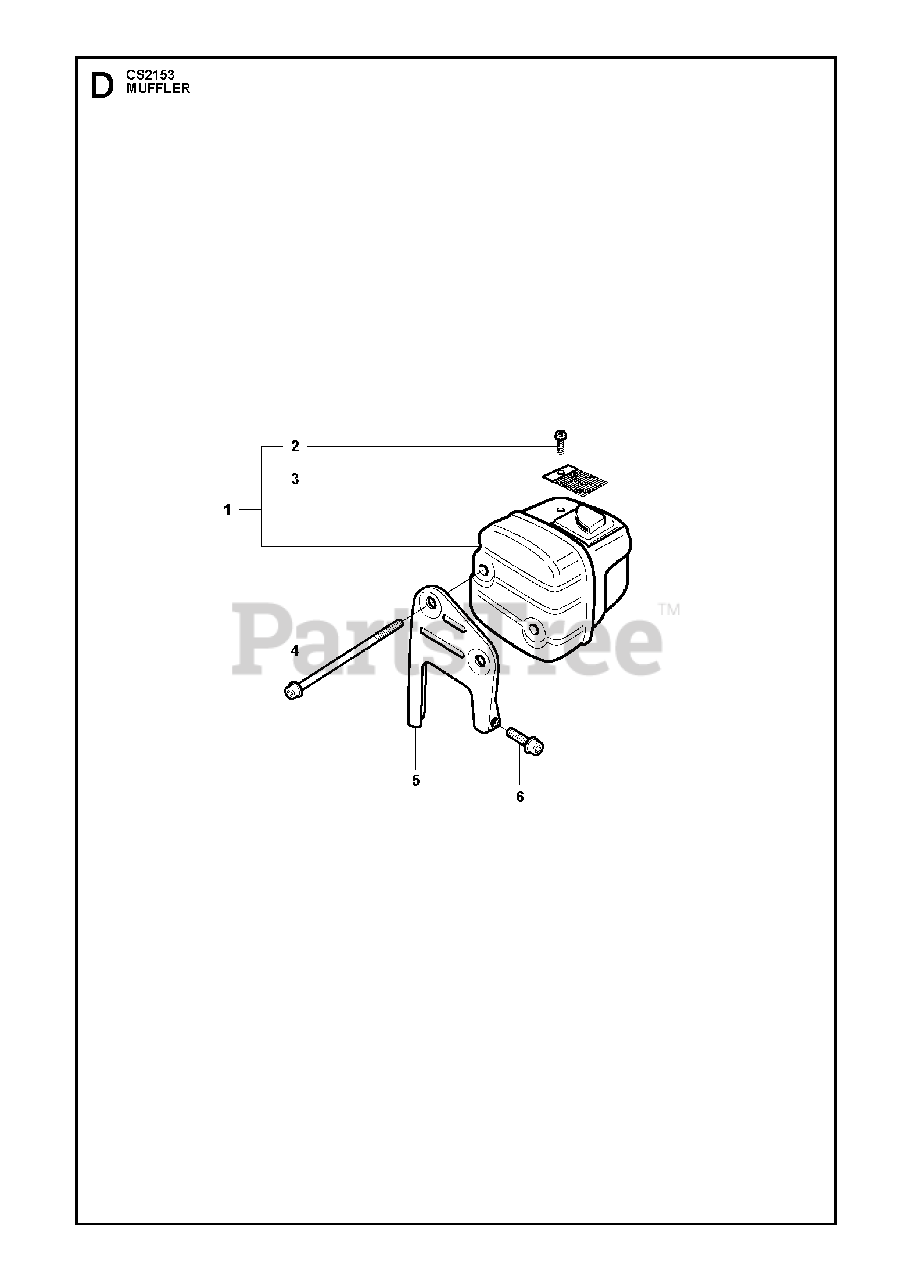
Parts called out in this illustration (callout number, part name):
1	MUFFLER ASSY
1	MUFFLER
2	SCREW
3	RP SCREEN
4	SCREW
